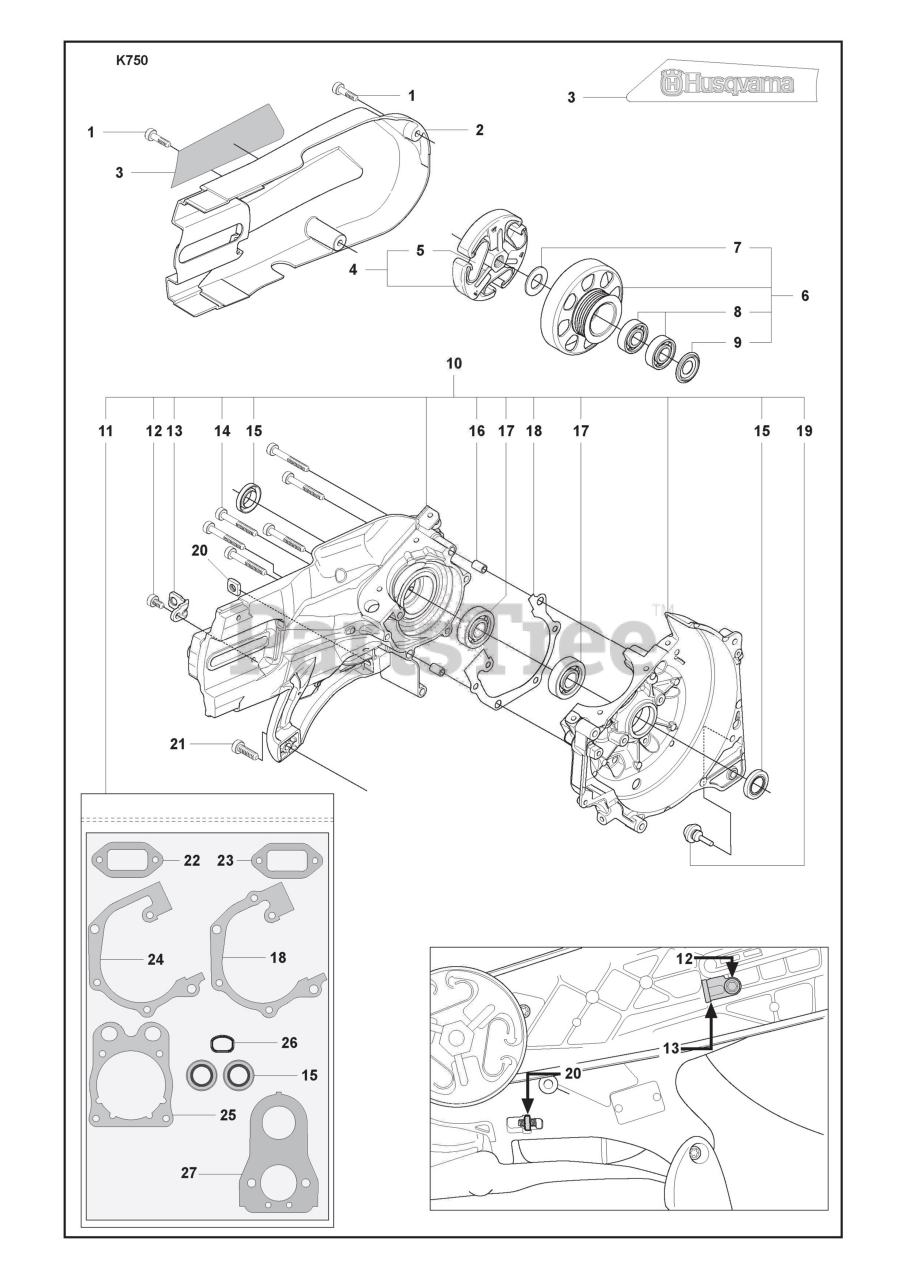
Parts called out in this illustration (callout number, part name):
2	BELT GUARD
4	CLUTCH ASSY
5	CLUTCH SPRING
6	DRIVING PULLEY ASSY
7	WASHER STEEL
8	BALL BEARING
9	DUST COVER
10	CRANKCASE ASSY
11	GASKET KIT
15	SEALING RING
16	GUIDE BUSHING
17	BALL BEARING
18	GASKET CRANKCASE
23	GASKET MUFFLER
24	GASKET CRANKCASE
25	CYLINDER BASE GASKET
27	GASKET CARBURETTOR
